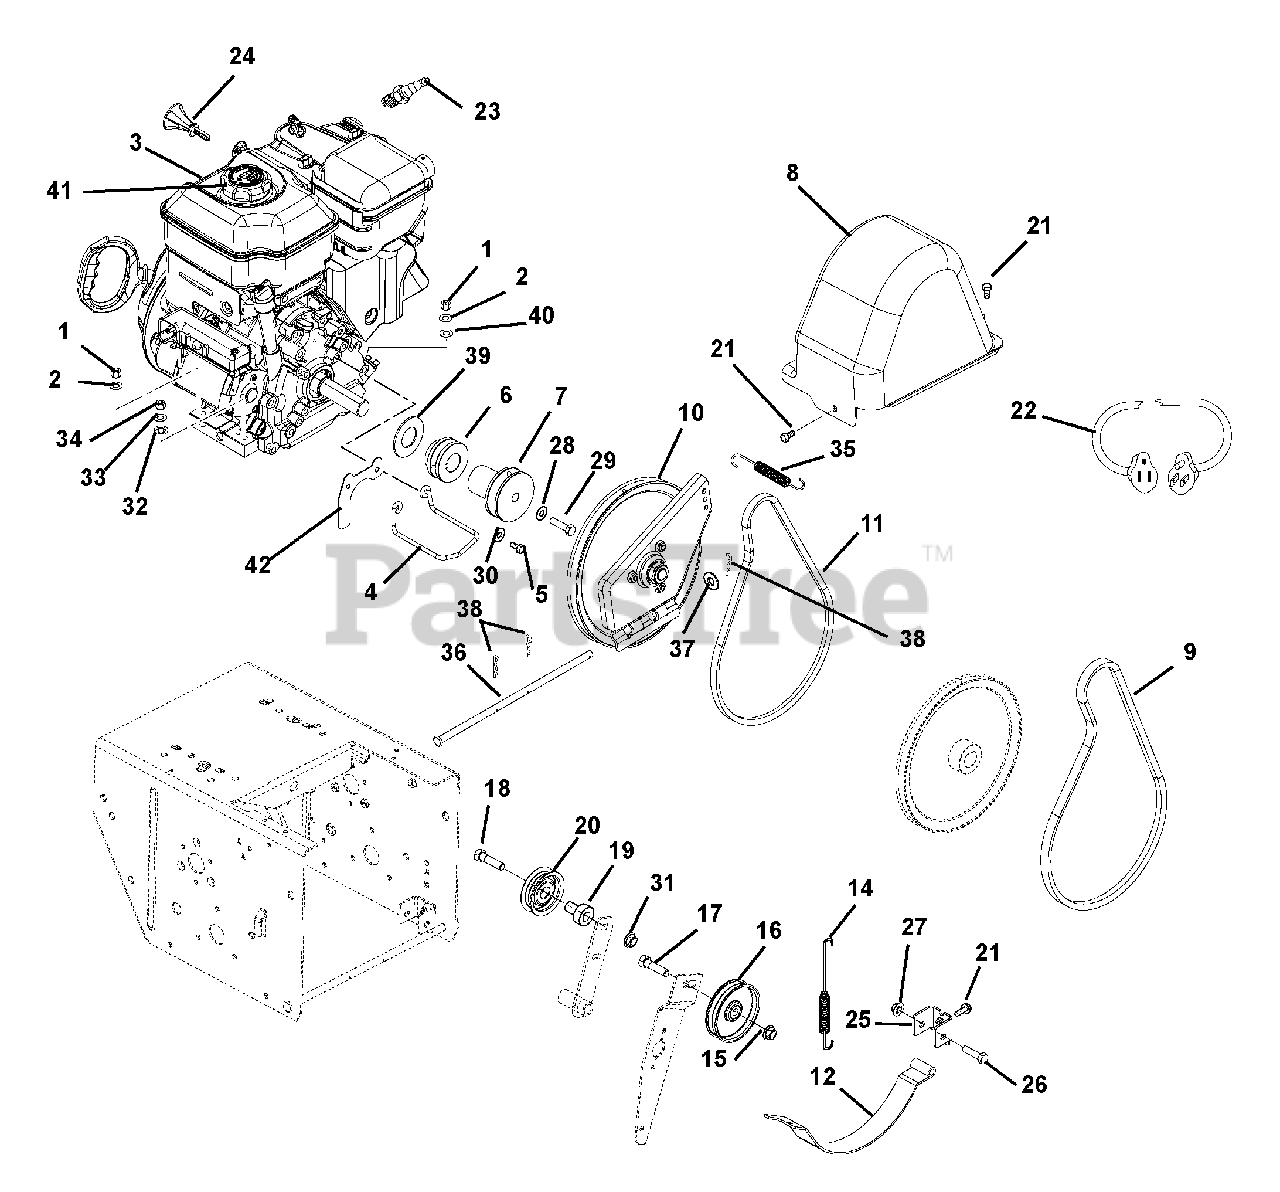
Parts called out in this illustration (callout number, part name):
1	@NUT-HEX .31-18 YWZC
2	WSHR-LK .312X.097 HVY YWZC
3	ENGINE,9.5HP 120V PWRBILT SNOW
4	FINGER, BELT
5	BLT-HEX .31-24X.75 YWZC GR5
6	SHEAVE, DRIVE
7	SHEAVE, ATTACHMENT
8	COVER, BELT
9	V-BELT, 4L-RAW EDGE
10	PLATE, SWING-ASSY
11	V-BELT, 3L-WRAPPED
12	ARM, BRAKE ATTACHMENT-W/PAD
13	PAD, BRAKE
14	SG-TENS .056X.60X4.40
15	@NUT-LK-TOP-FLG .38-16 YWZC
16	IDLER, FLAT-3.00
17	@BLT-HEX .38-16X1.50 GR5 YWZC
18	@BLT-HEX .31-18X1.25 GR5 YWZC
19	SPCR, BRG .315X.50X.688X.281
20	IDLER
21	@SCR-TAP .25-20X.50 HWH TR YWZ
22	CORD, ELECTRIC START CORD 120V
23	PLUG, SPARK
24	KEY, IGNITION PUSH/PULL B&S
25	PIVOT, BRAKE
26	@BLT-HEX .31-18X2.00 GR5 YWZC
27	@NUT-LK-TOP-FLG .31-18 YWZC
28	@WSHR-LK .38X.094 REG YWZC
29	BLT-HEX .38-24X2.0 YWZC
30	WSHR-LK .312X.097 HVY YWZC
31	@NUT-LK-TOP-FLG .31-18 YWZC
32	WSHR-LOCK INT .31 YWZC
33	@WSHR-FL-STL.344X.688X.065YWZC
34	@NUT-LK-CTR .31-18 YWZC
35	SG-TENS .048X.50X2.8
36	PIN, PIVOT
37	@WSHR-FL-STL.406X.812X.065 YWZ
38	PIN-HAIR, ENDRIES #25 YWZC
39	WSHR-FL-STL- 1.062X2.0X.134 YZ
40	@WSHR-FL-STL.38X.875X.083 YWZC
41	CAP, FUEL - BRIGGS
42	GUARD, BELT COVER-BRIGGS
